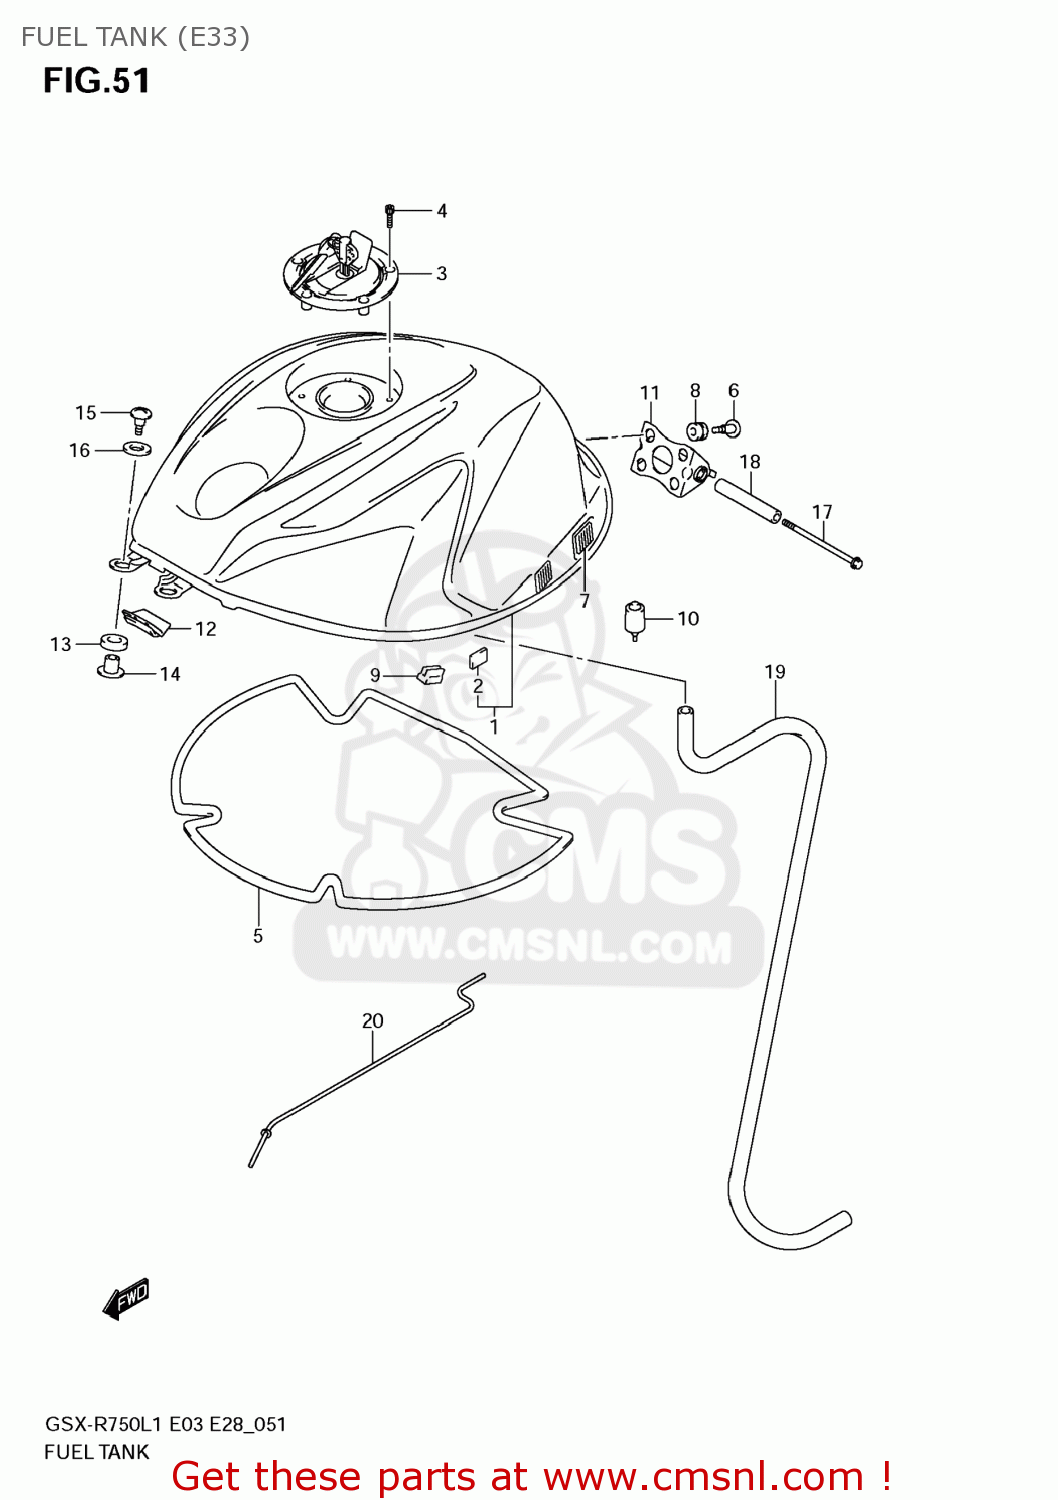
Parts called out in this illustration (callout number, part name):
1	TANK ASSY FUEL
2	FASTENER,FUEL TANK COVER
3	CAP SET,FUEL TANK
4	BOLT(5X20)
5	SHIELD,FUEL TANK HEAT
6	SCREW,FUEL TANK RR BRACKET
7	FASTENER
8	CUSHION
9	CUSHION,FUEL TANK COVER
10	CUSHION,FUEL TANK RR
11	BRACKET,FUEL TANK NO.1
12	RUBBER,FUEL TANK FR
13	CUSHION,FUEL TANK FR
14	SPACER,FUEL TANK FR
15	SCREW(6X25)
16	WASHER(6.5X22X1.6)
17	BOLT(6X110)
18	SPACER,FUEL TANK RR
19	HOSE,FUEL TANK WATER DRAIN
20	STAY,FUEL TANK
